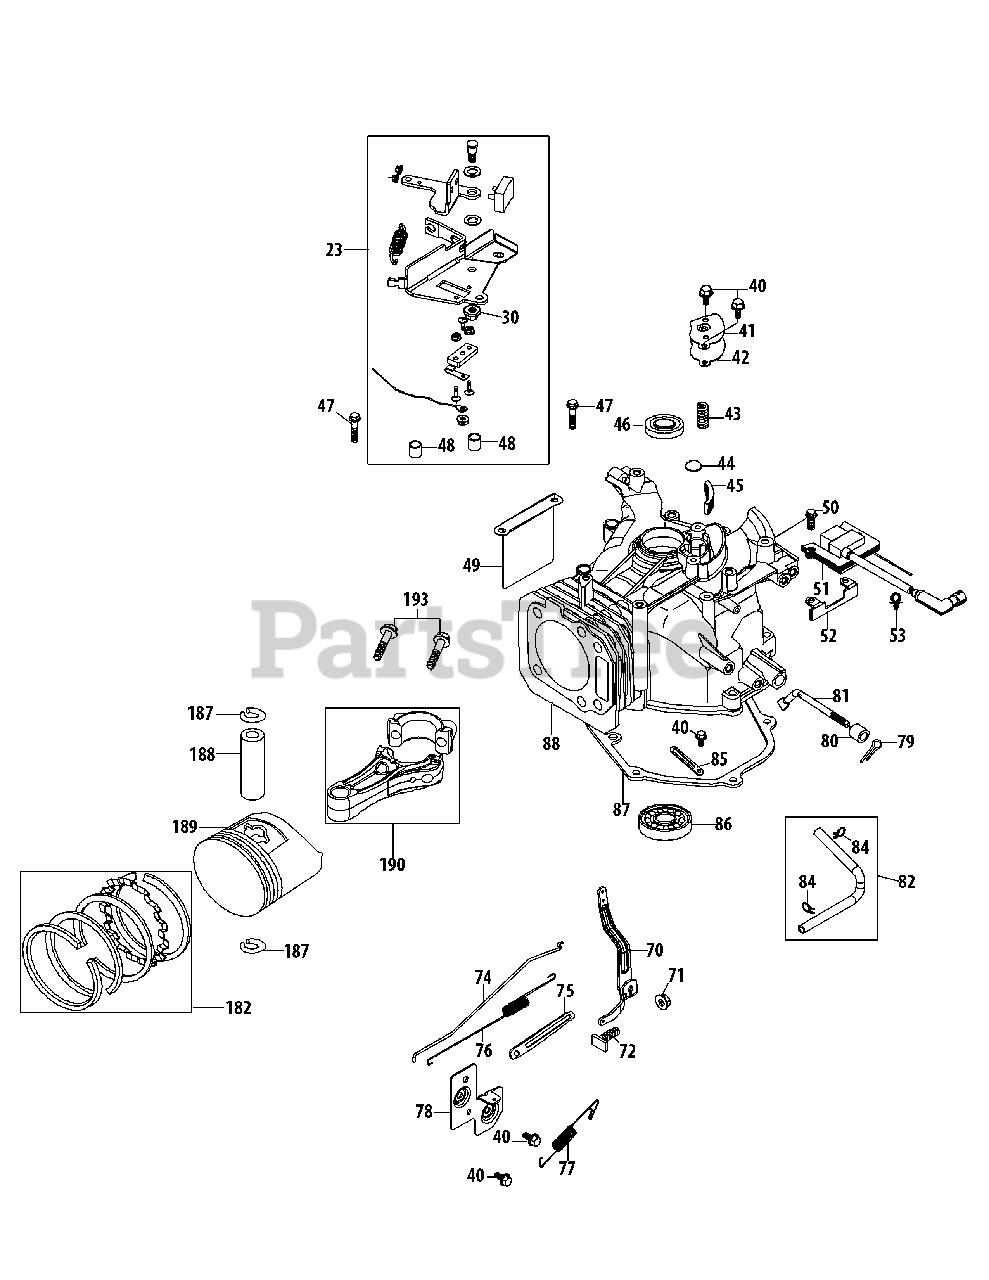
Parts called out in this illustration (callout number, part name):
23	Stop Switch And Brake Assembly
30	Nut M 8 - 1.25
40	Bolt M6×14
41	Breather Cover Plate
42	Breather Gasket
43	Breather Valve Spring
44	Breather Valve
45	Mesh Screen
46	Upper Crankshaft Seal
47	Bolt M6×35
48	Engine Brake Spacer
49	Label Bracket
50	Bolt M6×18
51	Ignition Coil Assembly
52	Ignition Coil Bracket
53	Plastic Clamp 6.3×8
70	Governor Arm
71	Nut M6
72	Governor Arm Bolt
74	Throttle Linkage
75	Flexible Clamp
76	Throttle Linkage Spring
77	Governor Return Spring
78	Component Bracket
79	Clip - Governor Shaft
80	Governor Seal
81	Governor Arm Shaft
82	Breather Hose Asm - Includes Hose & Clamps
84	Breather Hose Clamp
85	Flexible Clamp
86	Main Bearing
87	Crankcase Cover Gasket
88	Short Block Assembly
182	Piston Ring Set
187	Piston Pin Snap Ring
188	Piston Pin
189	Piston
190	Connecting Rod Assembly
193	Connecting Rod Bolt
